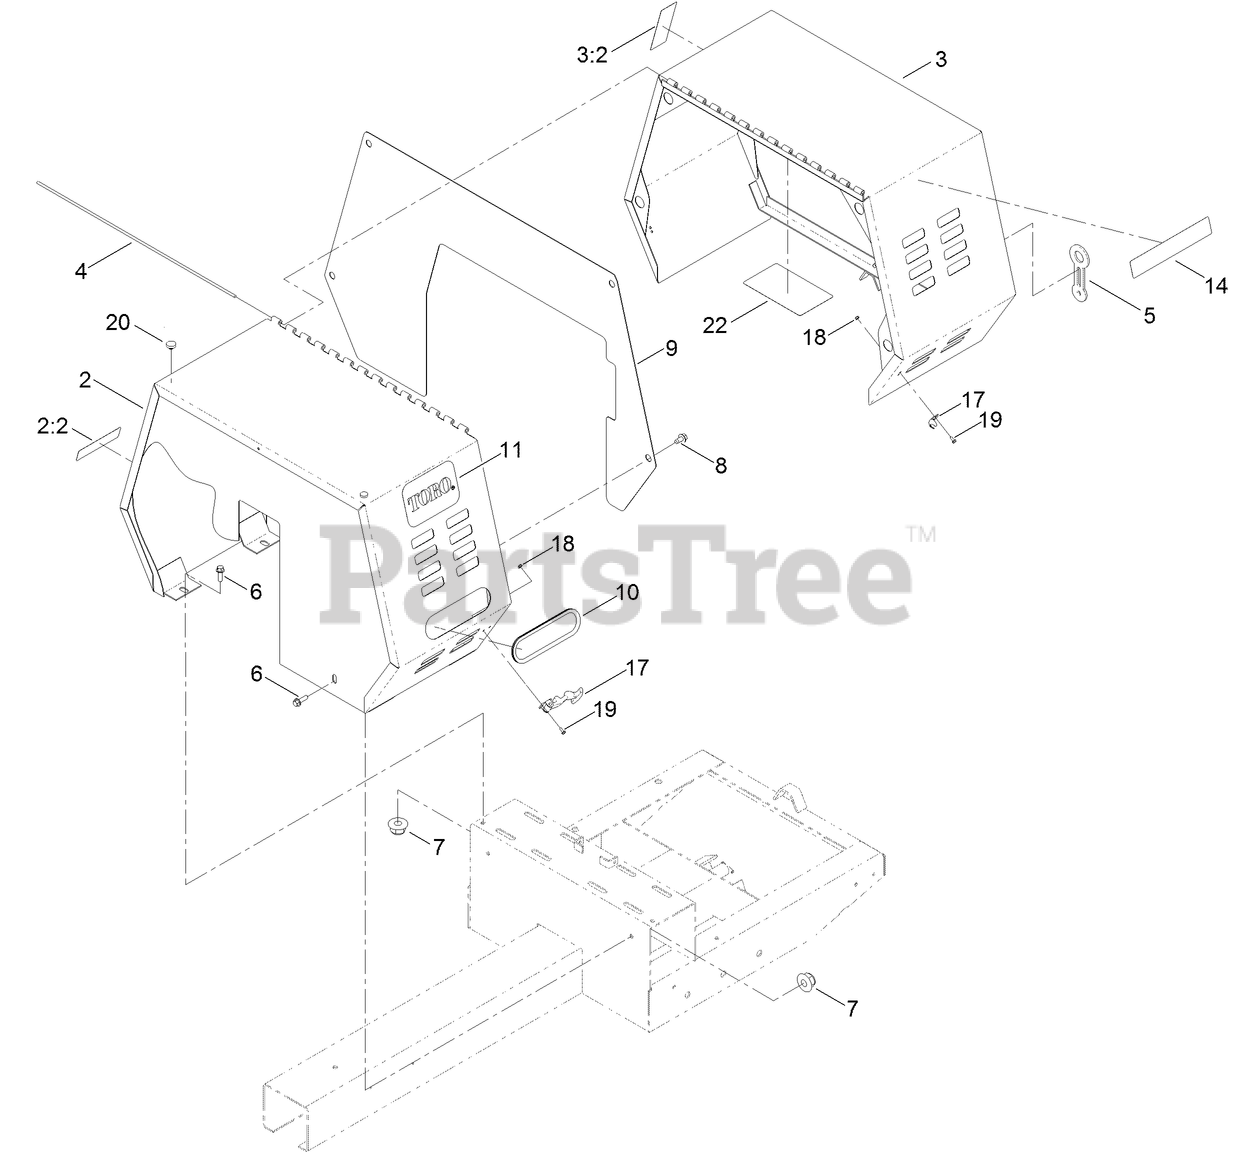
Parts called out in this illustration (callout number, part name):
2	STATIONARY COWL ASM
2:2	DECAL-ARRESTOR, SPARK
3	MOVABLE COWL ASM
3:2	DECAL-WARNING
5	LATCH-RUBBER
6	SCREW-HHF
7	NUT-HF, NI
8	SCREW-HWH
9	PLATE-COWL, 12CF MM
10	TRIM-LID
11	DECAL
17	LATCH-FLEX, DRAW
18	NUT-LOCK, NI
19	SCREW-HWH
20	BUMPER
22	DECAL-SERVICE
